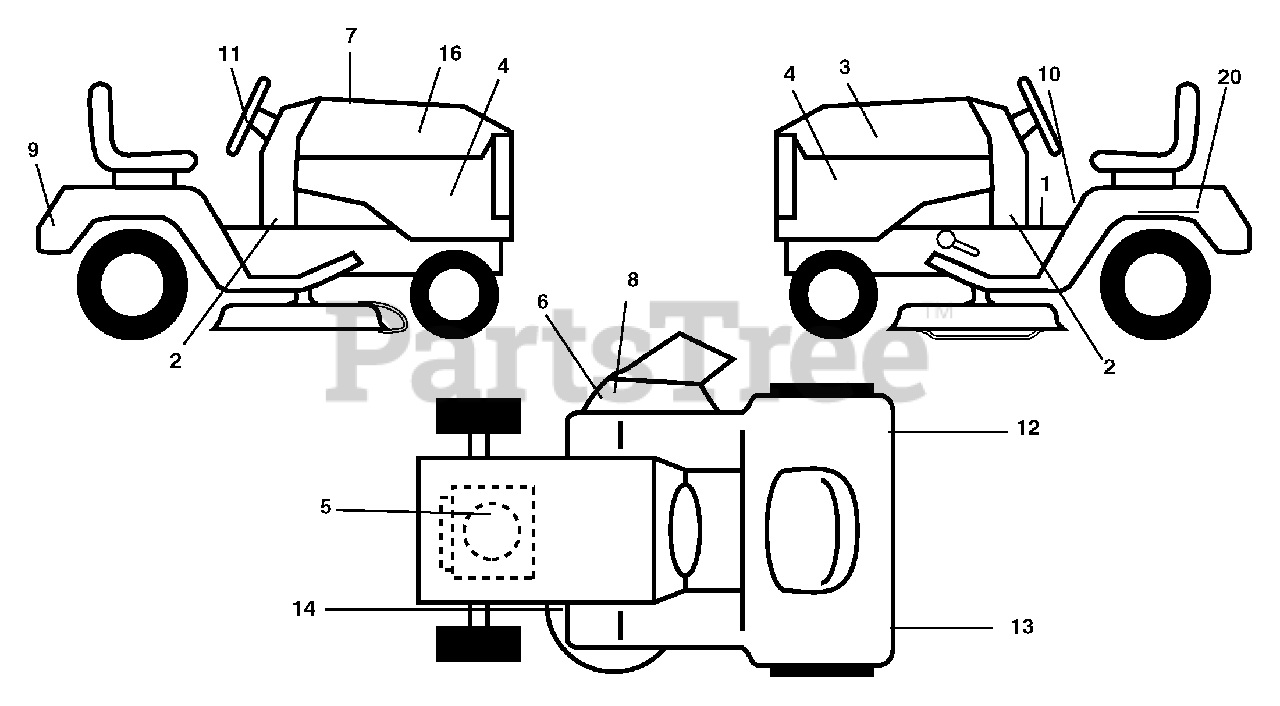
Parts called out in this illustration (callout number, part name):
1	Decal, Oper
2	Decal, Lower Dash
3	Decal, Hood LH
4	Decal, Side Panel Logo
5	Decal, HP Engine
6	Decal, Warning, Keep Hand Away
7	Decal, Replacement Parts
8	Decal, Deck "B" 42"
9	Decal, Fender Logo
10	Decal, Fender Danger E/F
11	Decal, Ins Strg Whl
12	Decal, Fend Refl ector Rh
13	Decal, Fend Refl ector Lh
14	Decal, V-Belt Schematic
16	Decal, Hood Rh
20	Decal, Bat Dan/Psn
